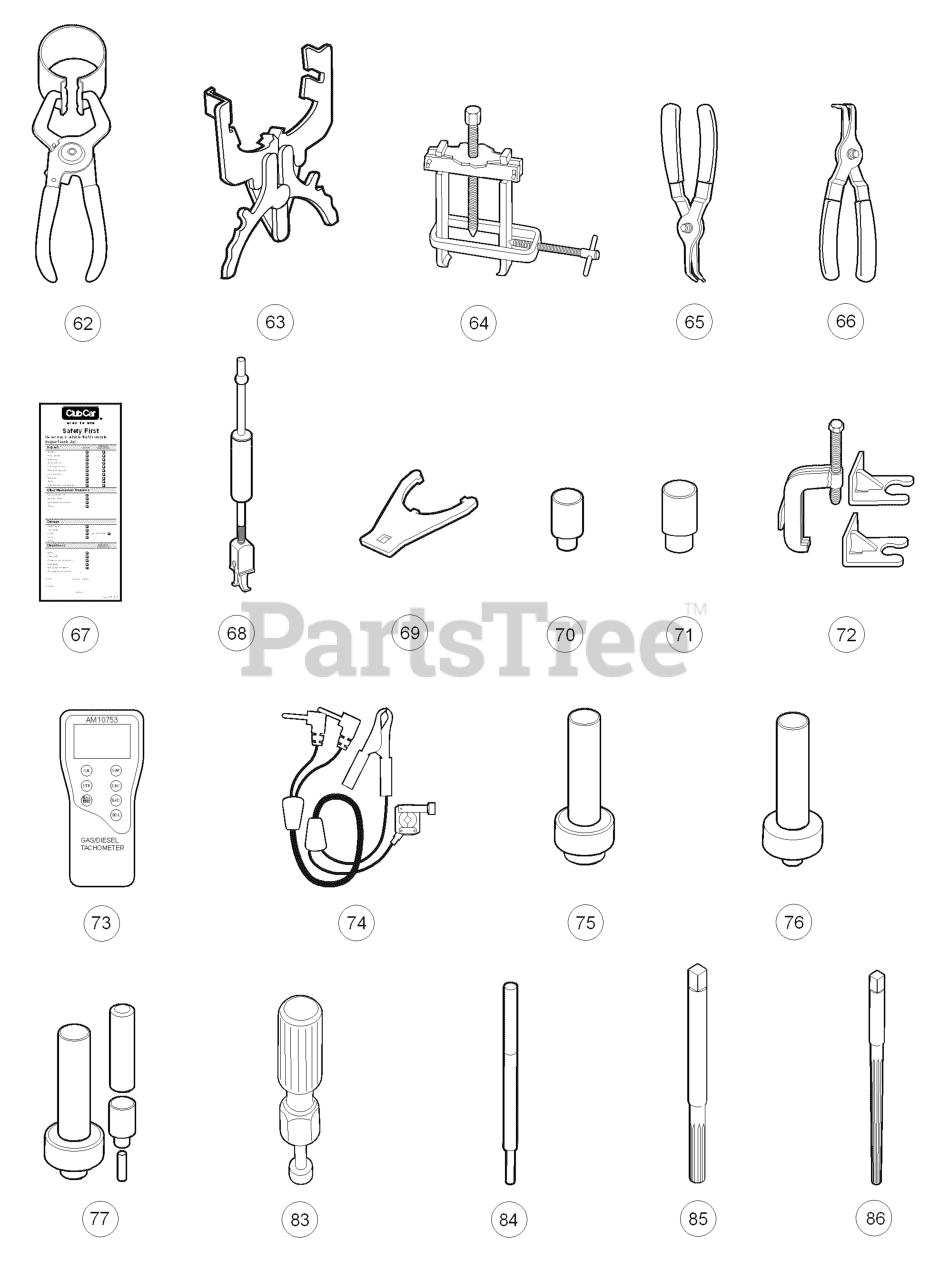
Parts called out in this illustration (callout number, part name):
62	KIT, PISTON RING COMPRESSOR
63	PISTON RING PLIER
64	SPECIAL-USE PULLER SET
65	EXTERNAL SNAP RING PLIERS
66	INTERNAL SNAP RING PLIER 9O
67	SAFETY FIRST CARD
68	SEAL PULLER
69	WRENCH, SPANNER
70	Steering Column Bearing Press Tool
71	TOOL-STEERING RETAINING RING
72	PULLER, STEERING WHEEL
73	TACHOMETER GAS/DIESEL
74	TACHOMETER DIESEL ADAPTOR
75	TRANS-AXLE, AXLE SEAL TOOL
76	Transaxle Pinion Seal Tool
77	Transmission Tool Kit
82	VALVE CLEAR ADJ SCREW HOLDER
83	DRIVER, VALVE GUIDE, 6.6. MM
84	VALVE GUIDE REAMER
85	REAMER-VALVE GUIDE
